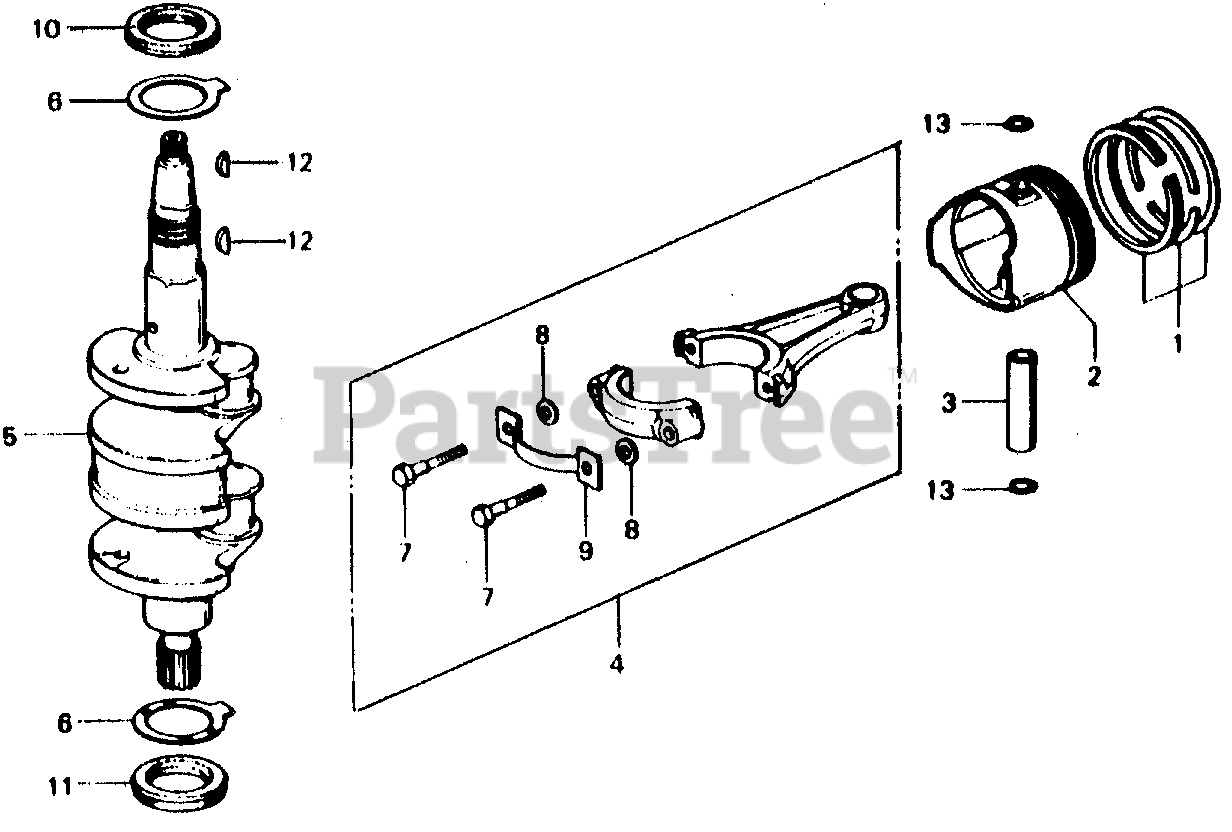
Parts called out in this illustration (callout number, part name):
1	RING SET, PISTON (2SET) (STD)
3	PIN, PISTON
4	ROD ASSY., CONNECTING
5	CRANKSHAFT
6	BEARING, CRANKSHAFT THRUST
7	BOLT, CONNECTING ROD
8	WASHER (6MM)
9	WASHER, LOCK
10	OIL SEAL A (30X42X7)
11	OIL SEAL B (30X42X7)
12	KEY, WOODRUFF (16X15)
13	CLIP, PISTON PIN (14MM)
